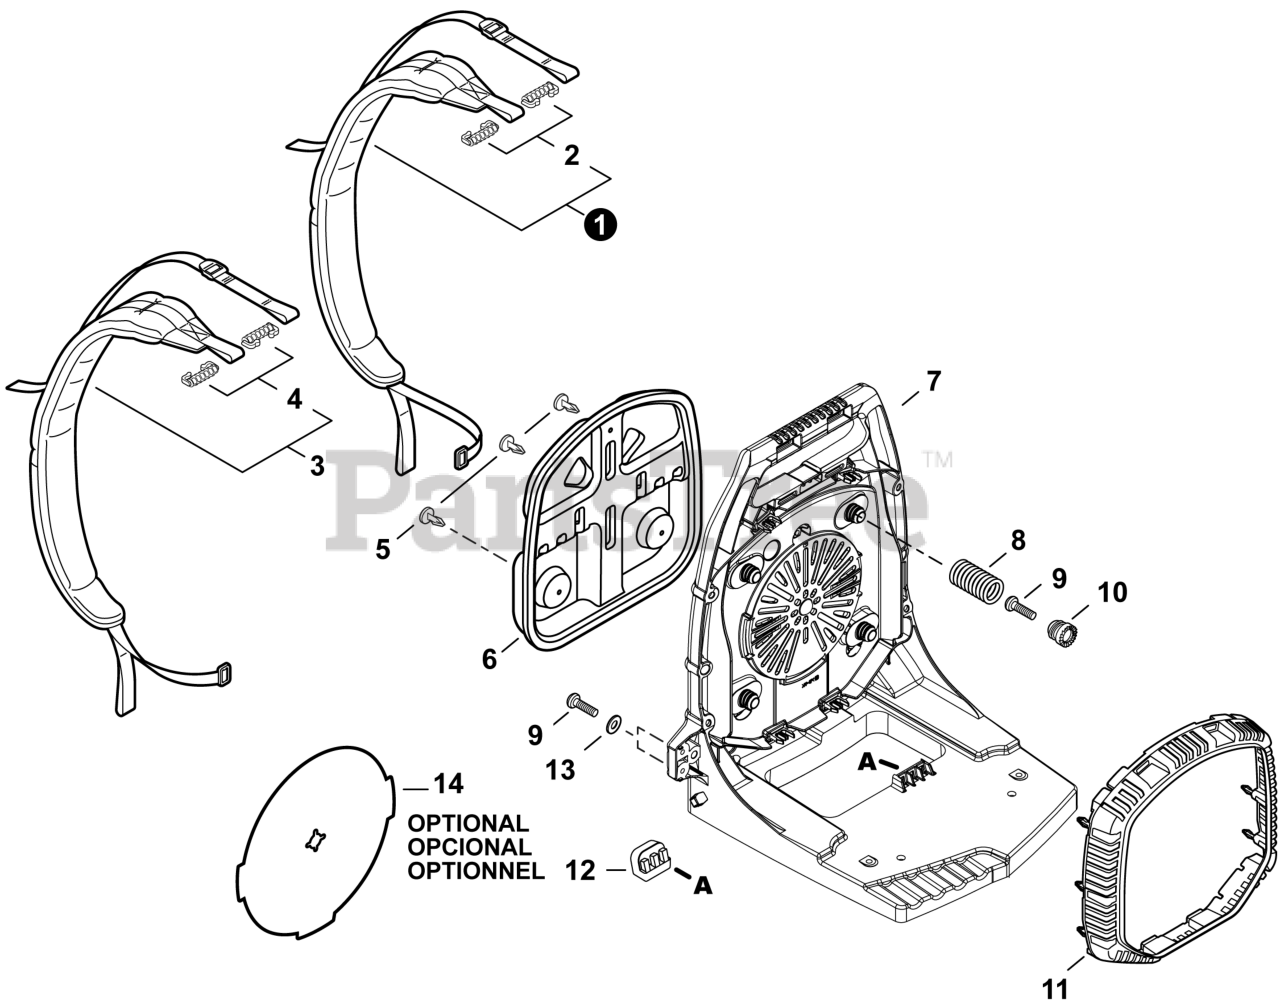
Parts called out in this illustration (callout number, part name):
1	HARNESS ASSY, RIGHT
2	CLIP
3	HARNESS ASSY, LEFT
4	CLIP
6	CUSHION, BACKPACK
7	FRAME, BACKPACK
8	SPRING, COMPRESSION
9	BOLT, TORX 5x20
10	HOLDER, SPRING
11	GUARD, DEBRIS
12	CUSHION
13	WASHER 5.5x16x2T
14	INSERT, COLD WEATHER
